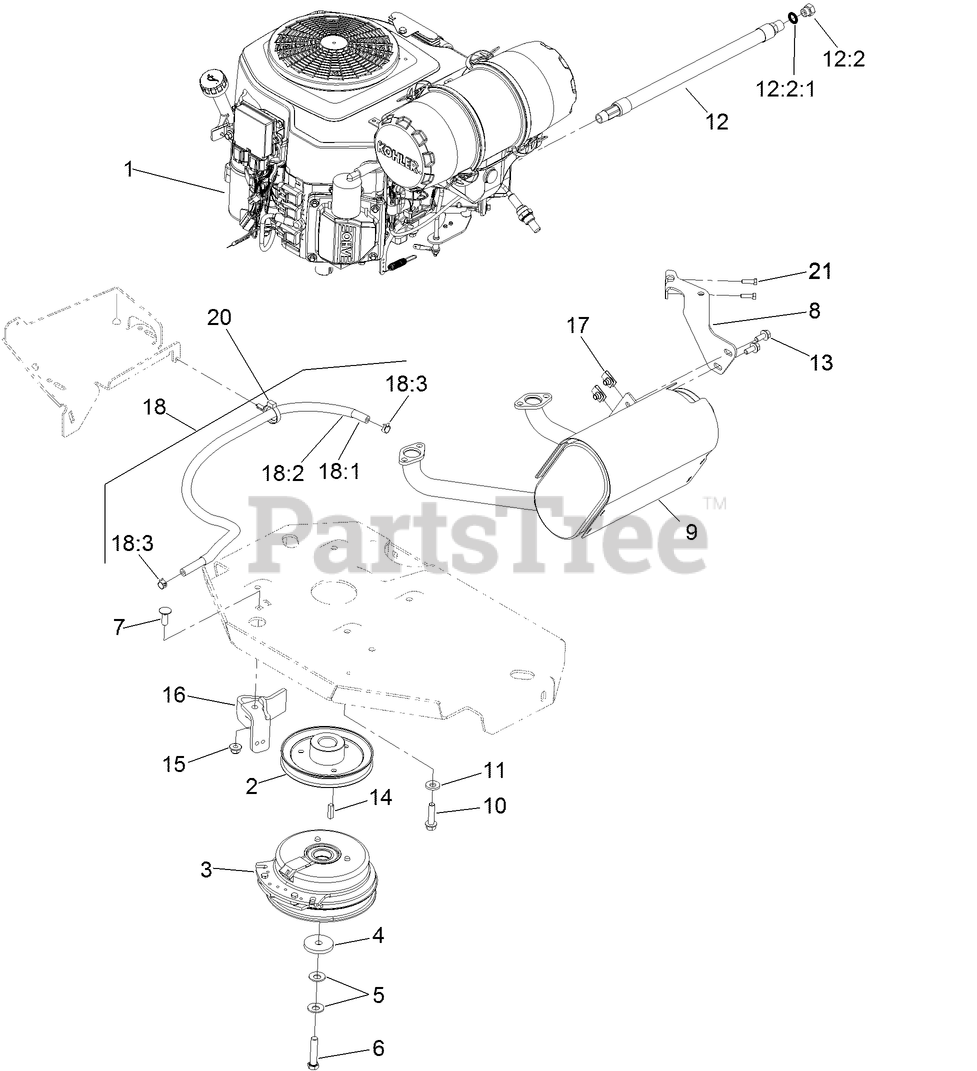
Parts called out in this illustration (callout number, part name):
2	SHEAVE
3	CLUTCH KIT
4	WASHER-CLUTCH
5	WASHER-SPRING
6	SCREW-HH W/LOCTITE
7	SCREW-CARR
8	MUFFLER BRACKET KIT
9	MUFFLER
10	SCREW-HWH
11	WASHER-BELLEVILLE
12	OIL DRAIN HOSE ASM
12:2	PLUG-HH
12:2:1	O-RING
13	SCREW-HHF
15	NUT-HF, NI
16	CLUTCH-ANCHOR
17	NUT-U
18	FUEL LINE ASM
18:1	HOSE-FUEL
18:2	SLEEVE-THERMAL
18:3	CLAMP-HOSE
20	CLAMP-HOSE
21	SCREW-HH
